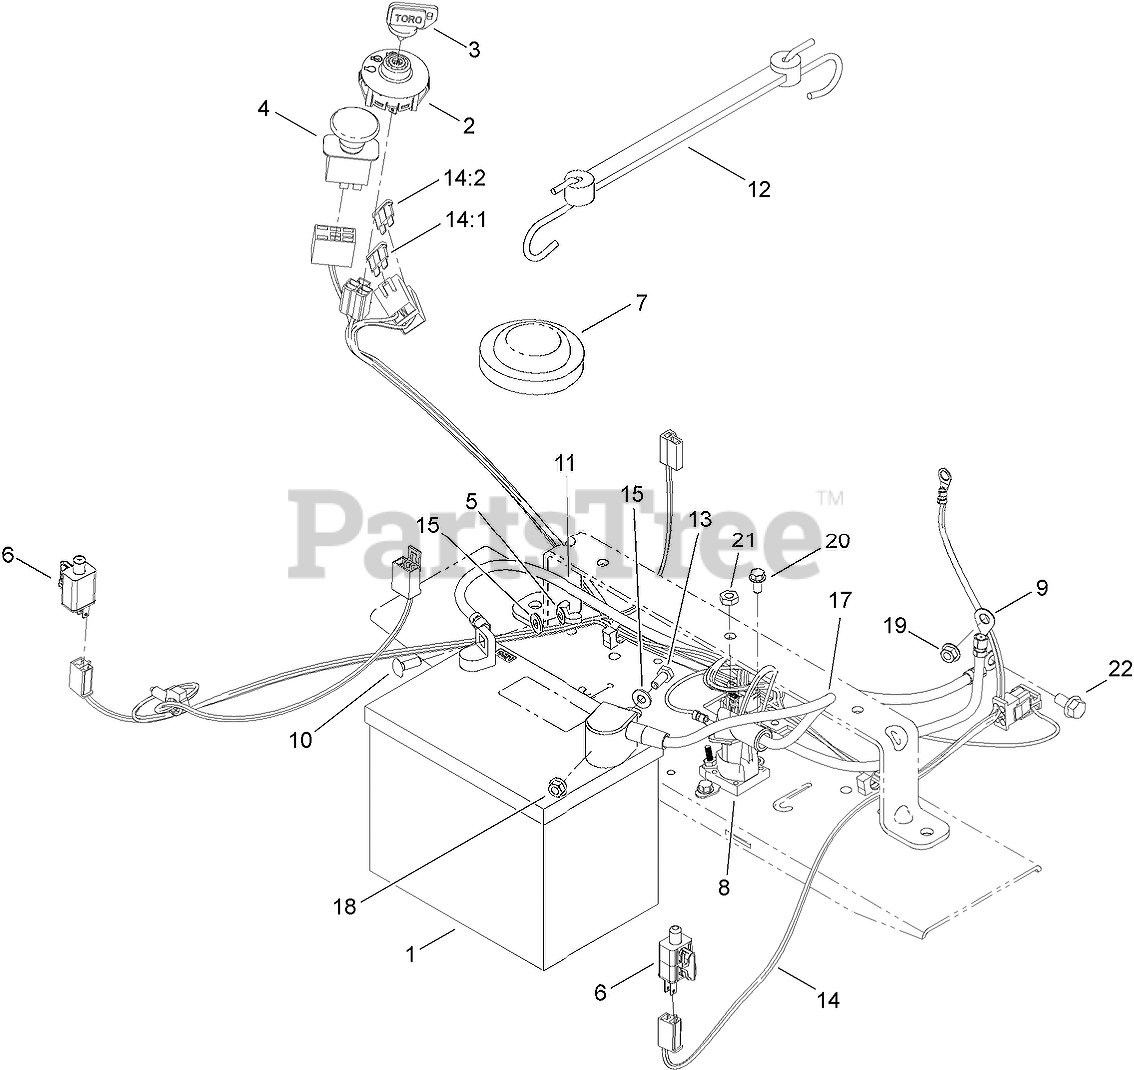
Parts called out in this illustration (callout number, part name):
1	BATTERY
2	SWITCH-IGNITION
3	KEY-IGNITION
4	SWITCH-PTO
5	NUT-WING
6	SWITCH
7	SWITCH-SEAT
8	SOLENOID
9	CABLE-BATTERY, POSITIVE
10	BOLT-CARR
11	CABLE-BATTERY, BLACK
12	HOLDDOWN-BATTERY
13	SCREW-HH
14	HARNESS-WIRE
14:1	FUSE-BLADE, 30 AMP
14:2	FUSE-BLADE, 25 AMP
15	WASHER-FLAT
17	CABLE-BATTERY, RED
18	NUT-HF
19	NUT-HF
20	SCREW-HWH
21	NUT-JAM
22	SCREW-HHF
